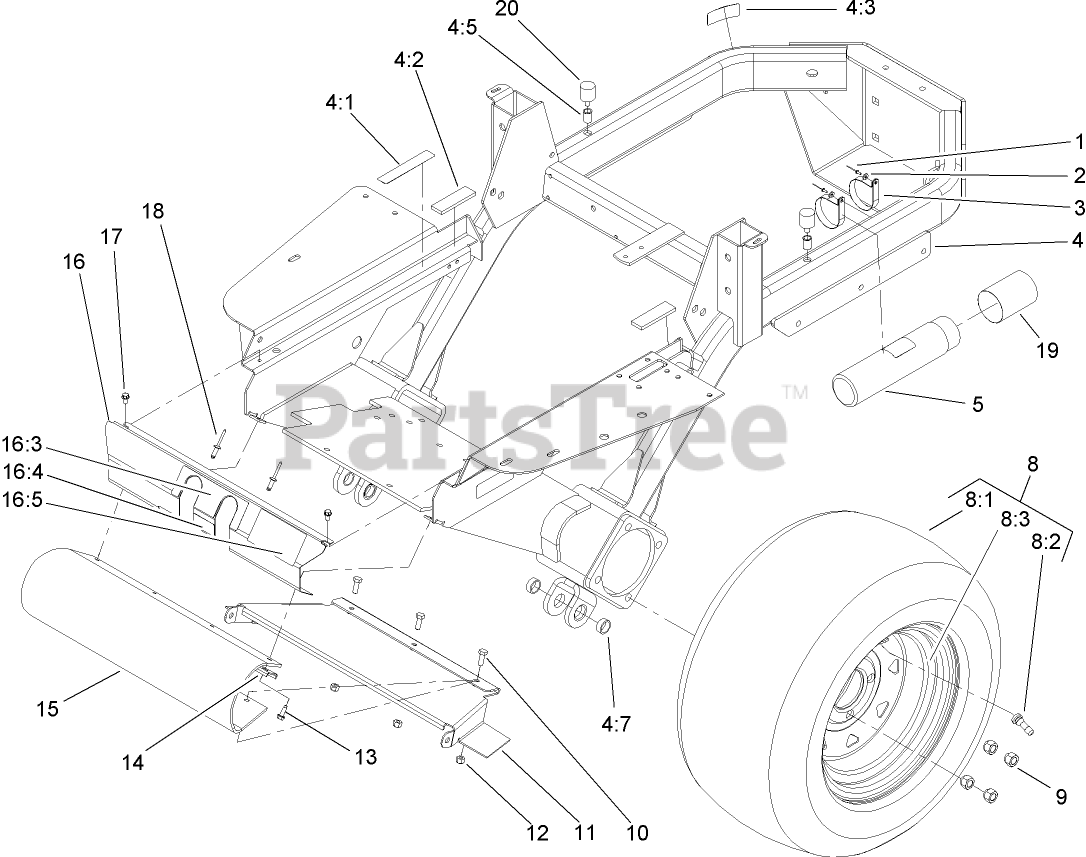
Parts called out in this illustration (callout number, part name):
1	RIVET-BLIND
2	WASHER-FLAT
3	CLAMP-R
4	FRAME ASM
4:1	DECAL-WARNING
4:2	PAD-RUBBER
4:3	DECAL-HOT SURFACE
4:5	INSERT-THREADED
4:7	BUSHING
5	TUBE-MANUAL
8	Tire And Wheel ASM
8:1	Tire
8:2	STEM-VALVE
8:3	WHEEL
9	NUT-LUG
10	SCREW-HH
11	COVER-DRIVESHAFT
12	NUT-LOCK, NI
13	SCREW-HWH, THREAD ROLL
14	BRACKET-GUARD
15	GUARD-FOOTREST
16	COVER PLATE ASM
16:3	DECAL - OPERATION
16:4	DECAL-PROTECTION, EAR
16:5	DECAL-PAK, DENSE
17	SCREW-HWH
18	RIVET-BLIND
19	CAP-HOUSING
20	BUMPER-RUBBER
